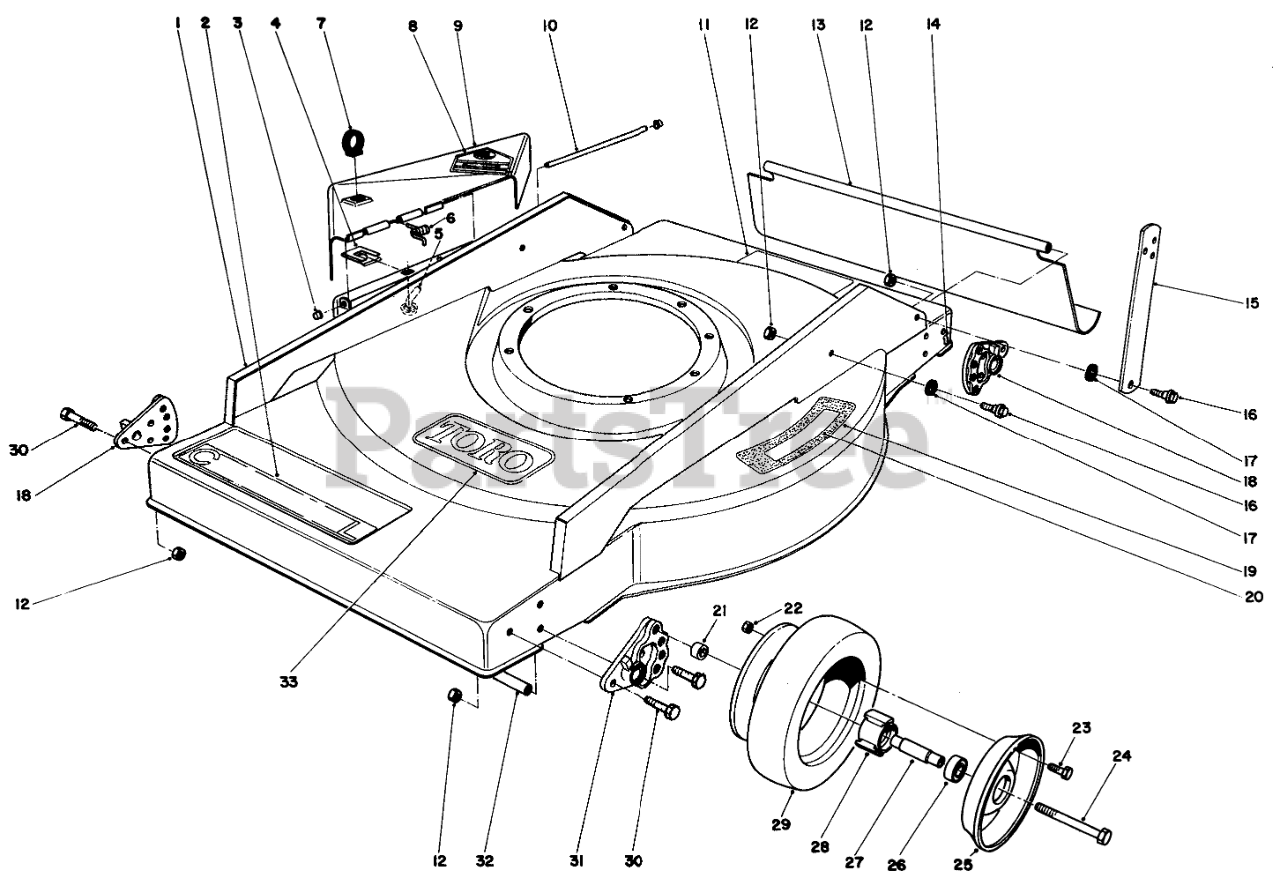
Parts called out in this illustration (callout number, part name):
1	Housing (Incl. Ref. #2, 19 & 20)
2	COMMERCIAL DECAL
3	PUSHNUT-CAP, WASHER
4	BAG CHUTE CLIP PIN
5	BAG CHUTE PIN
6	TORSION SPRING
7	LIFT LOOP
8	DECAL-DANGER
9	Deflector (Incl. Ref. #8)
10	DEFLECTOR PIVOT ROD
11	DECAL-INSTRUCTION, SAFETY
12	NUT-LOCK, NI
13	REAR SAFETY SHIELD
14	SHIELD ROD
15	Handle Strap
16	SCREW-SHOULDER
17	HANDLE LATCH SPACER
18	WHL QUADRANT B-MACH.
19	PAD STEP
20	Decal Step Pad
21	SPACER-WHEEL
22	NUT-LOCK, NI
23	SCREW-HHF
24	SCREW-HH
25	Wheel-Half
26	BEARING-WHEEL
27	SPACER-BEARING
28	HUB-BEARING
30	SCREW-HH
31	WHL QUADRANT A-MACH.
32	Rod-Tie
33	Decal Tow
